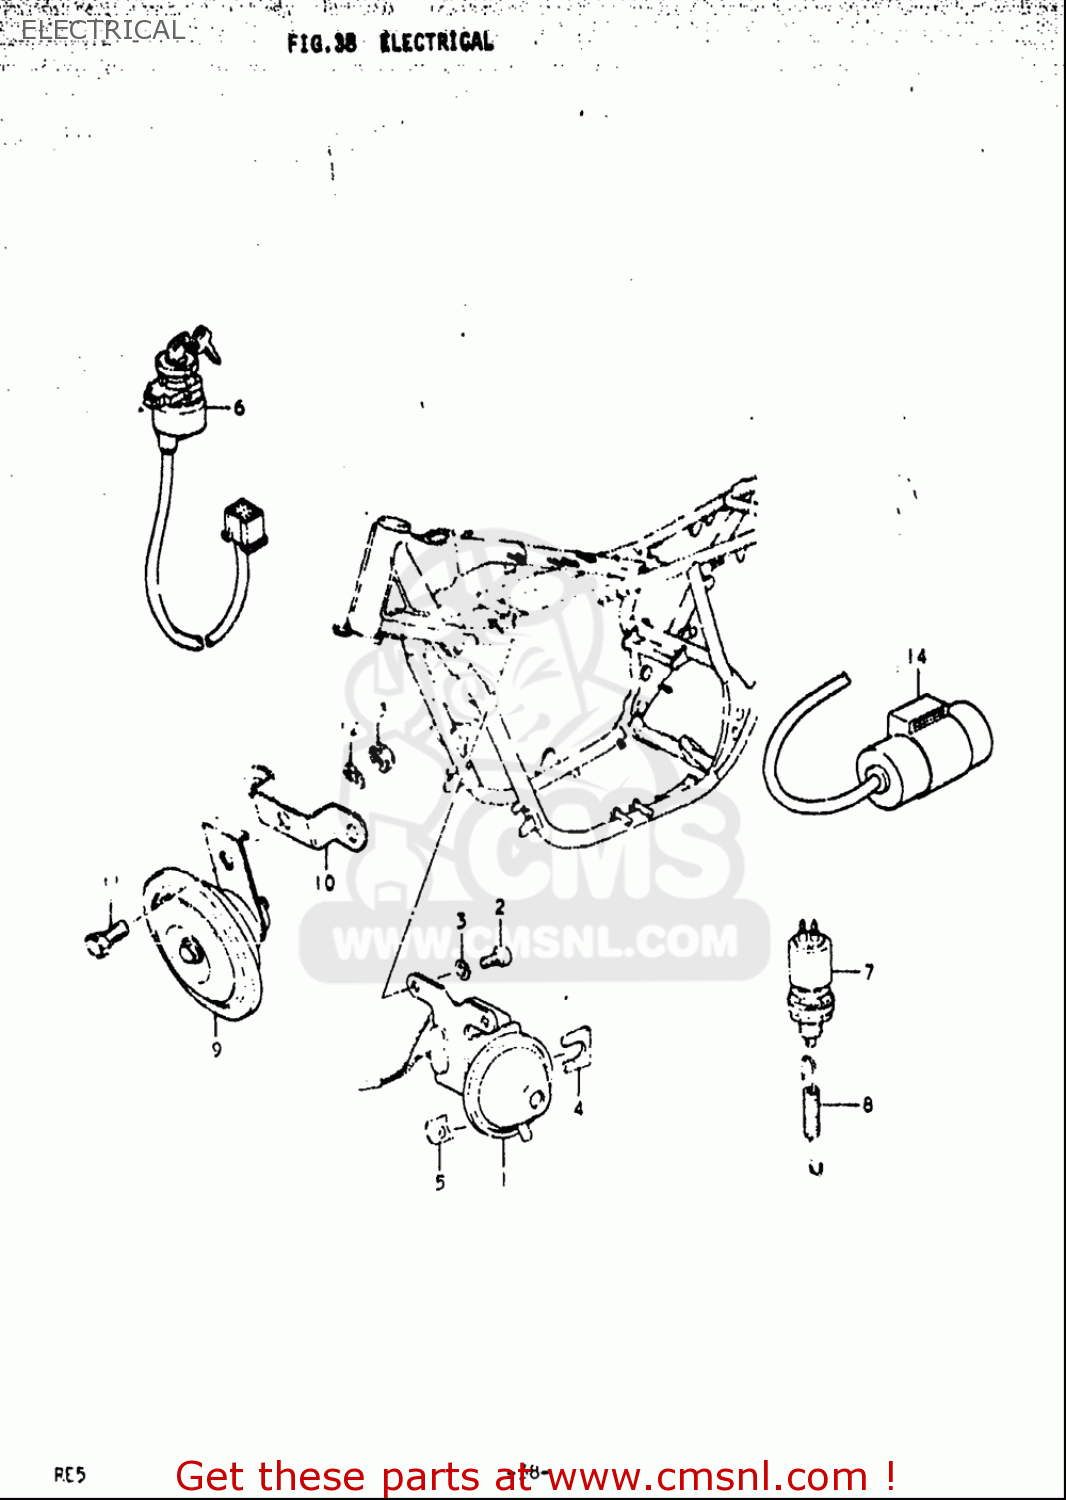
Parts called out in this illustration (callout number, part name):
2	BOLT
3	WASHER,LOCK
7	SWITCH ASSY,BRAKE LAMP
8	SPRING
9	HORN ASSY
11	BOLT
12	WASHER,LOCK
13	NUT
